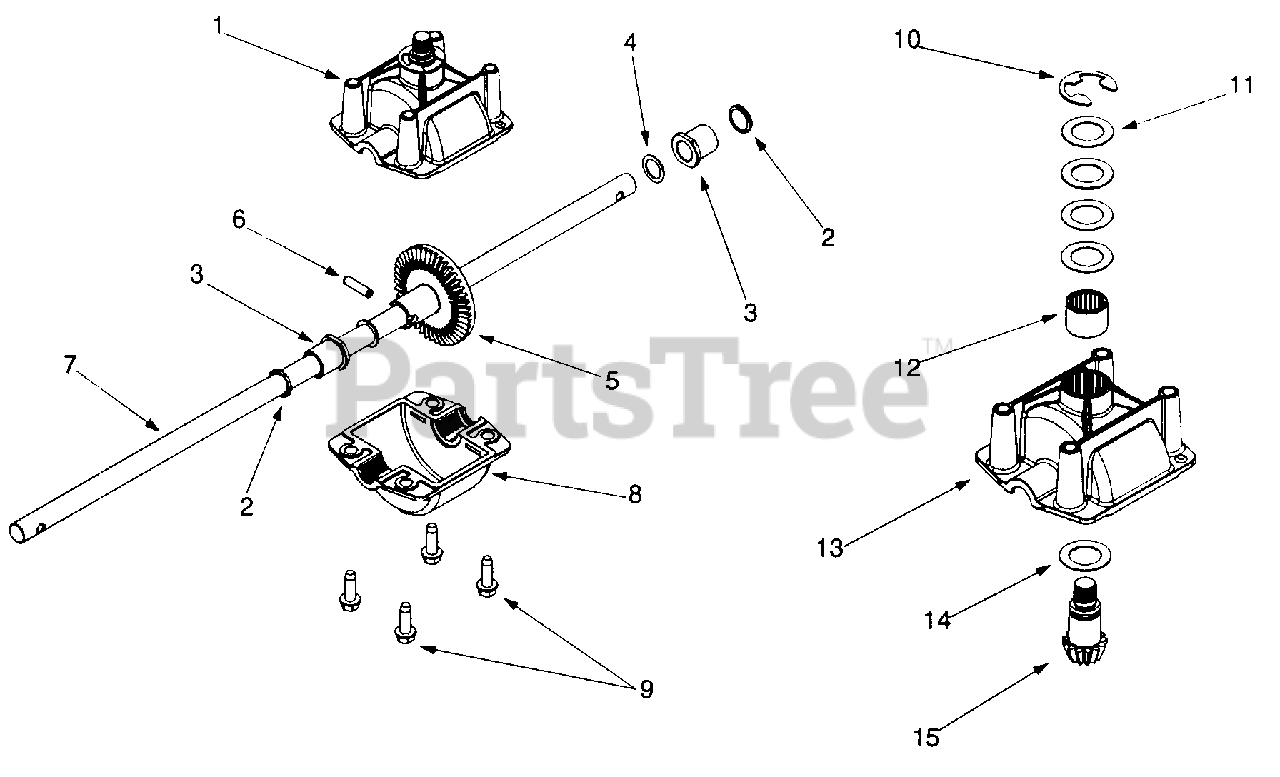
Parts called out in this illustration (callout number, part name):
1	Upper Housing Assembly
2	Oil Seal .500 ID x .687 OD
3	Flange Bearing .503 ID x .689 OD
4	Flat Washer .504 ID x .700 OD x .030
5	Bevel Gear 44T
6	Roll Pin
7	Output Shaft
8	Lower Housing
9	Hex Washer Screw 1/4-20 x .75
10	E-Ring .750
11	Flat Washer .625 ID x 1.0 OD x .030
12	Needle Bearing .625 x .813
13	Upper Housing
14	Flat Washer .625 ID x 1.0 OD x .030
15	Input Shaft
